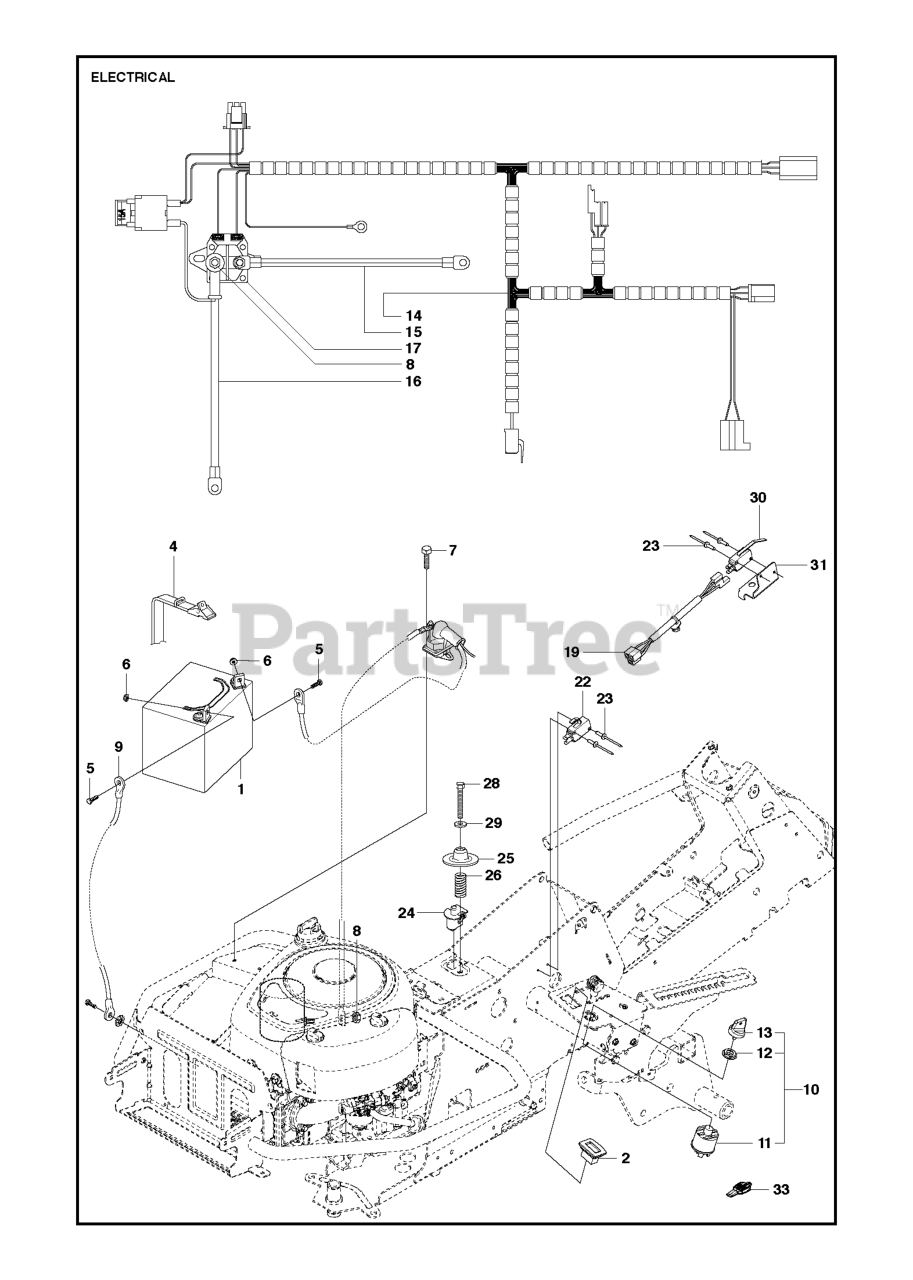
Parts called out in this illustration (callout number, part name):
2	HOUR METER
5	SCREW EHHM
10	IGNITION SWITCH
11	IGNITION SWITCH
13	IGNITION KEY
16	WIRE BATTERY
19	WIRING
22	MICRO SWITCH
29	WASHER BRB 8.4X17
30	MICRO SWITCH
